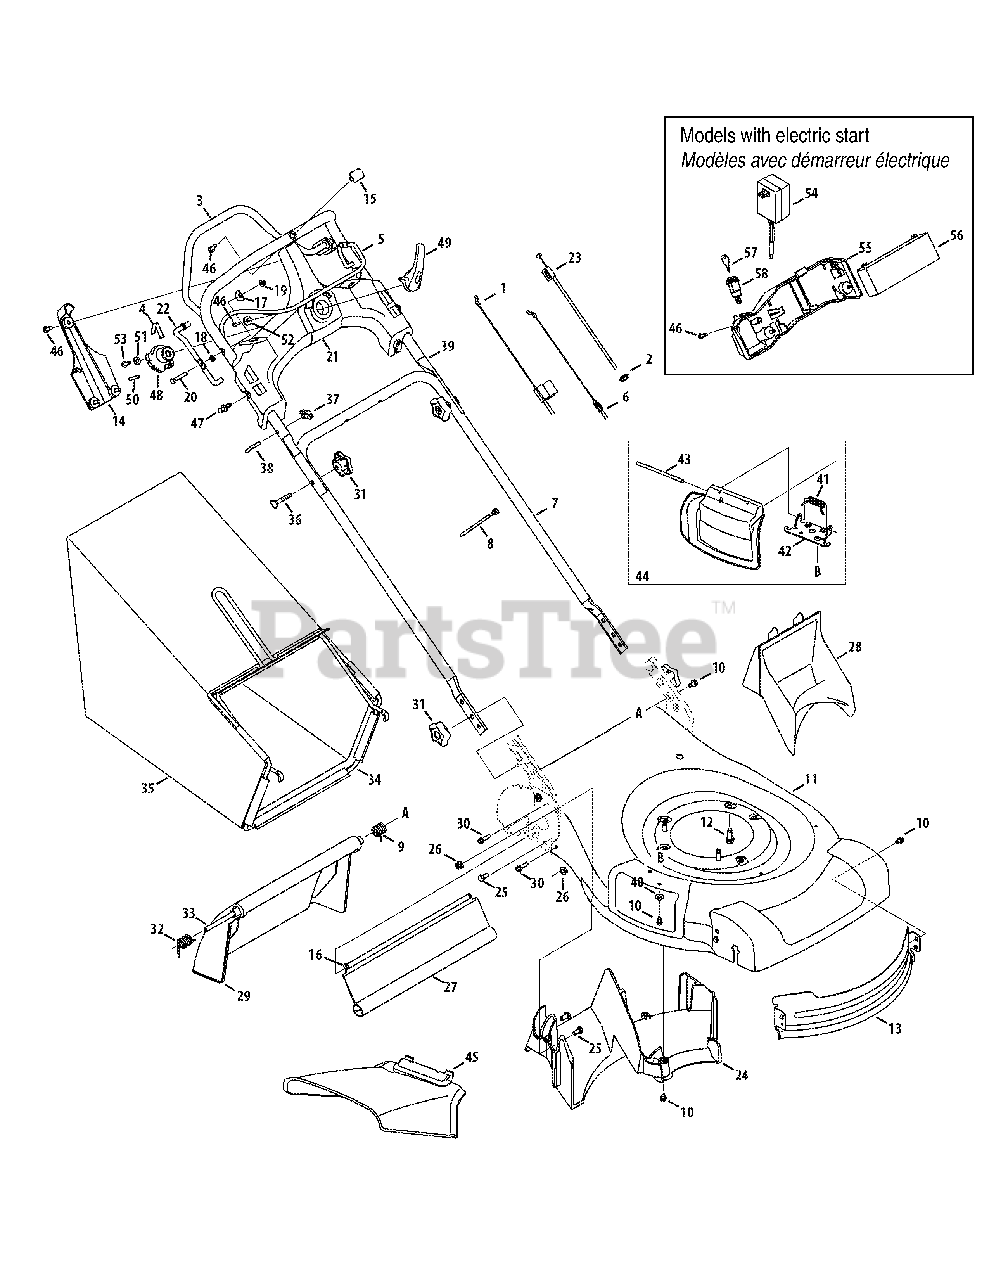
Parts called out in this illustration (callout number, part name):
1	Drive Cable
2	Rubber Grommet
3	Drive Control Ass'y
5	Blade Control Handle
6	Control Cable
9	Torsion Spring LH
10	Hex Wash S-Tapp Scr 1/4-20 x .50
13	Deck Baffle Kit
14	Variabale Speed Contol Panel Cover
15	Variabale Speed Contol Panel Cover
16	Screw, #10-16 x .50
17	Saddle Washer
18	L-Wash 1/4 ID
19	Flanged Lock Nut 1/4-20 Gr. F Nylon
20	Hex Cap Screw1/4-20 x 1.5" Lg.
21	Control Panel (w/o Electric Start)
21	Control Panel (w/Electric Start)
22	Bail Pivot Rod - RH
22	Bail Pivot Rod LH
23	Variable Speed Cable
25	Screw, 5/16-18 x .625
26	Hex Flange L-Nut 5/16-18 Gr. F
28	Rear Mulching Plug
29	Rear Discharge Door
30	Hex Lock Screw 1/4-15 x 1.0
31	Knob - Star 5/16-18
32	Torsion Spring RH
33	Door Pivot Rod
35	Grass Bag - WOP Grey
36	Carriage Bolt 5/16-18 x 2.0
38	Rope Guide Bolt
40	Cup. Wash. .265 ID x .75 OD x .062
41	Torsion Spring
42	Chute Hinge
43	Hinge Pin
44	Complete Mulch Plug
45	Side Chute Deflector
46	Screw, #12-16 x .75
47	Rivet, plastic
48	4 Speed Actuator
49	Speed Selector Level
52	Flat Washer .250 x .750 x .119
53	Screw, 1/4-15 x .750
54	Battery Charger
55	Har ness Assembly
56	Battery, 12V
57	Ignition Key
58	Key Switch
